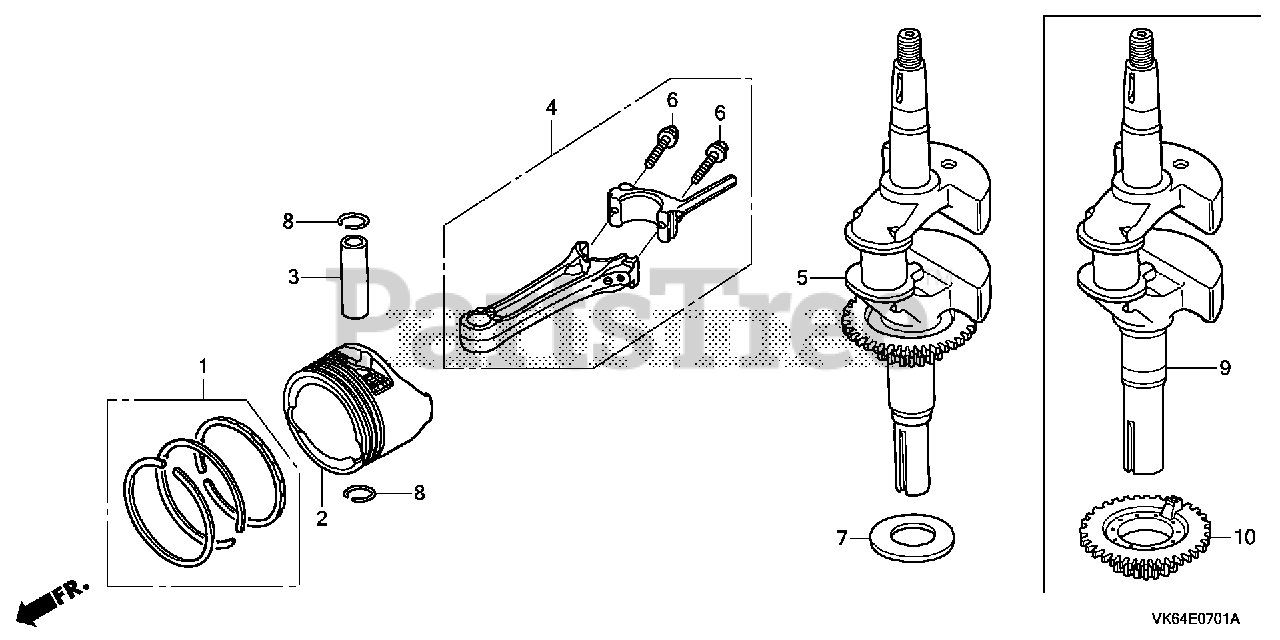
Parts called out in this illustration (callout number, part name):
1	RING SET, PISTON (STD) (TEIKOKU)
1	RING SET, PISTON (STD) (TPR)
2	PISTON
3	PIN, PISTON
4	ROD ASSY., CONNECTING
5	CRANKSHAFT KIT(N4
5	CRANKSHAFT
6	BOLT, CONNECTING ROD
7	WASHER, THRUST
8	CLIP, PISTON PIN (13MM)
